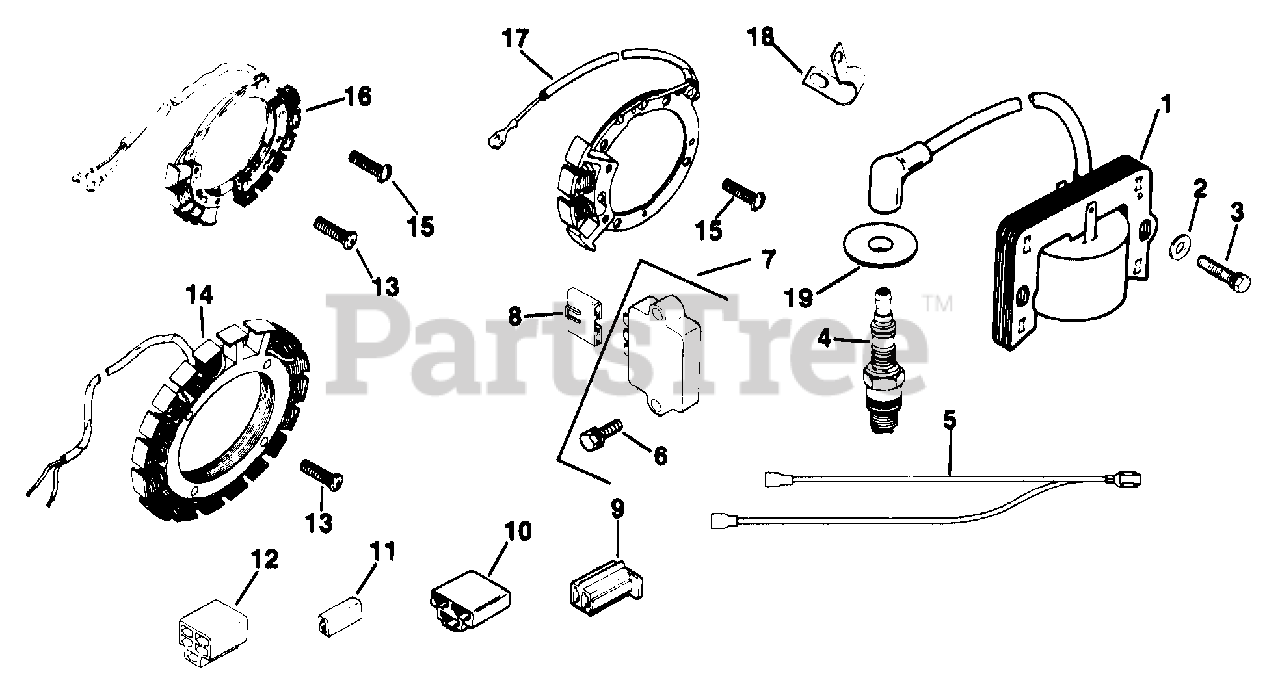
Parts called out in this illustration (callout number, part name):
1	MODULE - USE 41 584 03
2	WASHER, FLAT 3/16"
3	SCREW - USE X-67-51-S
4	SPARK PLUG - USE Champion RCJ8
5	HARNESS - DISCONTINUED
9	CONNECTOR
15	SCREW, WSH HD TAP #10-24-1/2"-DISC.
17	KIT - USE 25 755 11
